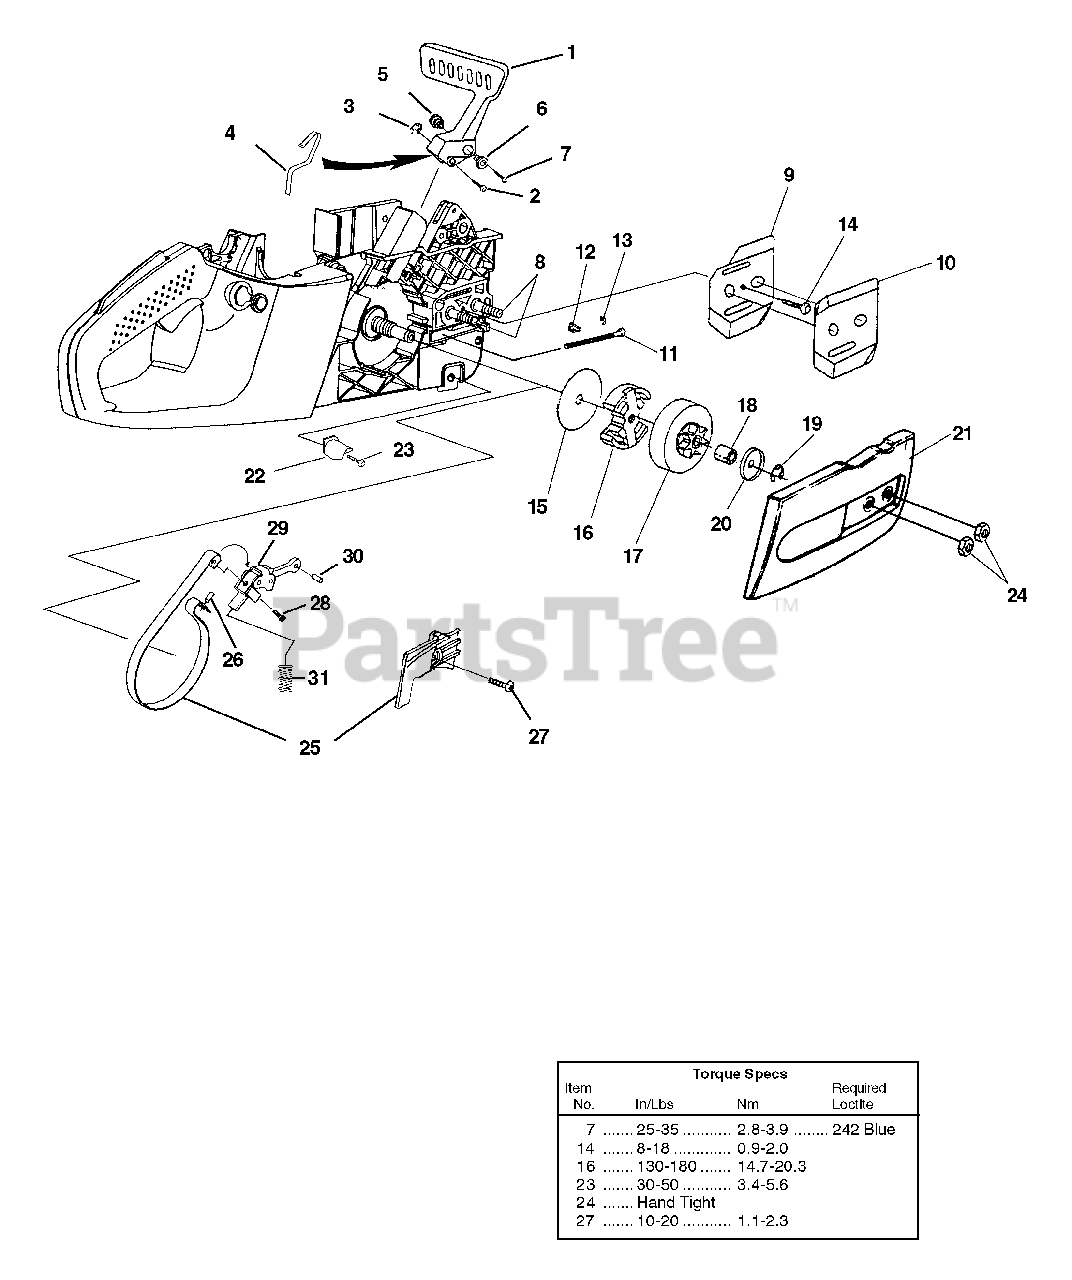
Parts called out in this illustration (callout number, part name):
1	Hand Guard Kit
2	Hand Guard Actuating Pin
3	Retaining Ring
4	Spring, Handguard
5	Pivot, L.H.
6	Pivot, R.H.
7	Screw, Hex Socket Hd. (8-32 x 5/8")
8	Guide Bar Bolt
9	Plate, Guide Bar
10	Plate, Guide Bar
11	Screw, Guide Bar Adjusting
12	Pin, Guide Bar Adjusting
13	Ring, Retaining
14	Screw, Thread Form., Plastite (6-19 x 1/2")
15	Thrust Washer
16	Clutch & Hardware
17	Sprocket, Drum (3/8 Pitch)
18	Bearing, Needle
19	Ring, Retaining
20	Washer, Cupped
21	Drive Case Cover
22	Stop, Chain
23	Screw, Thread Form., Plastite (10-14 x 3/4")
24	Nut, Hex
25	Chain Brake Kit
26	Pin, Roll
27	Screw, Pan Hd. (6-19 x 1/2")
28	Screw, Pan Hd. (8-16 x .320)
29	Chain Brake Link
30	Pin, Roll
31	Spring, Compression
